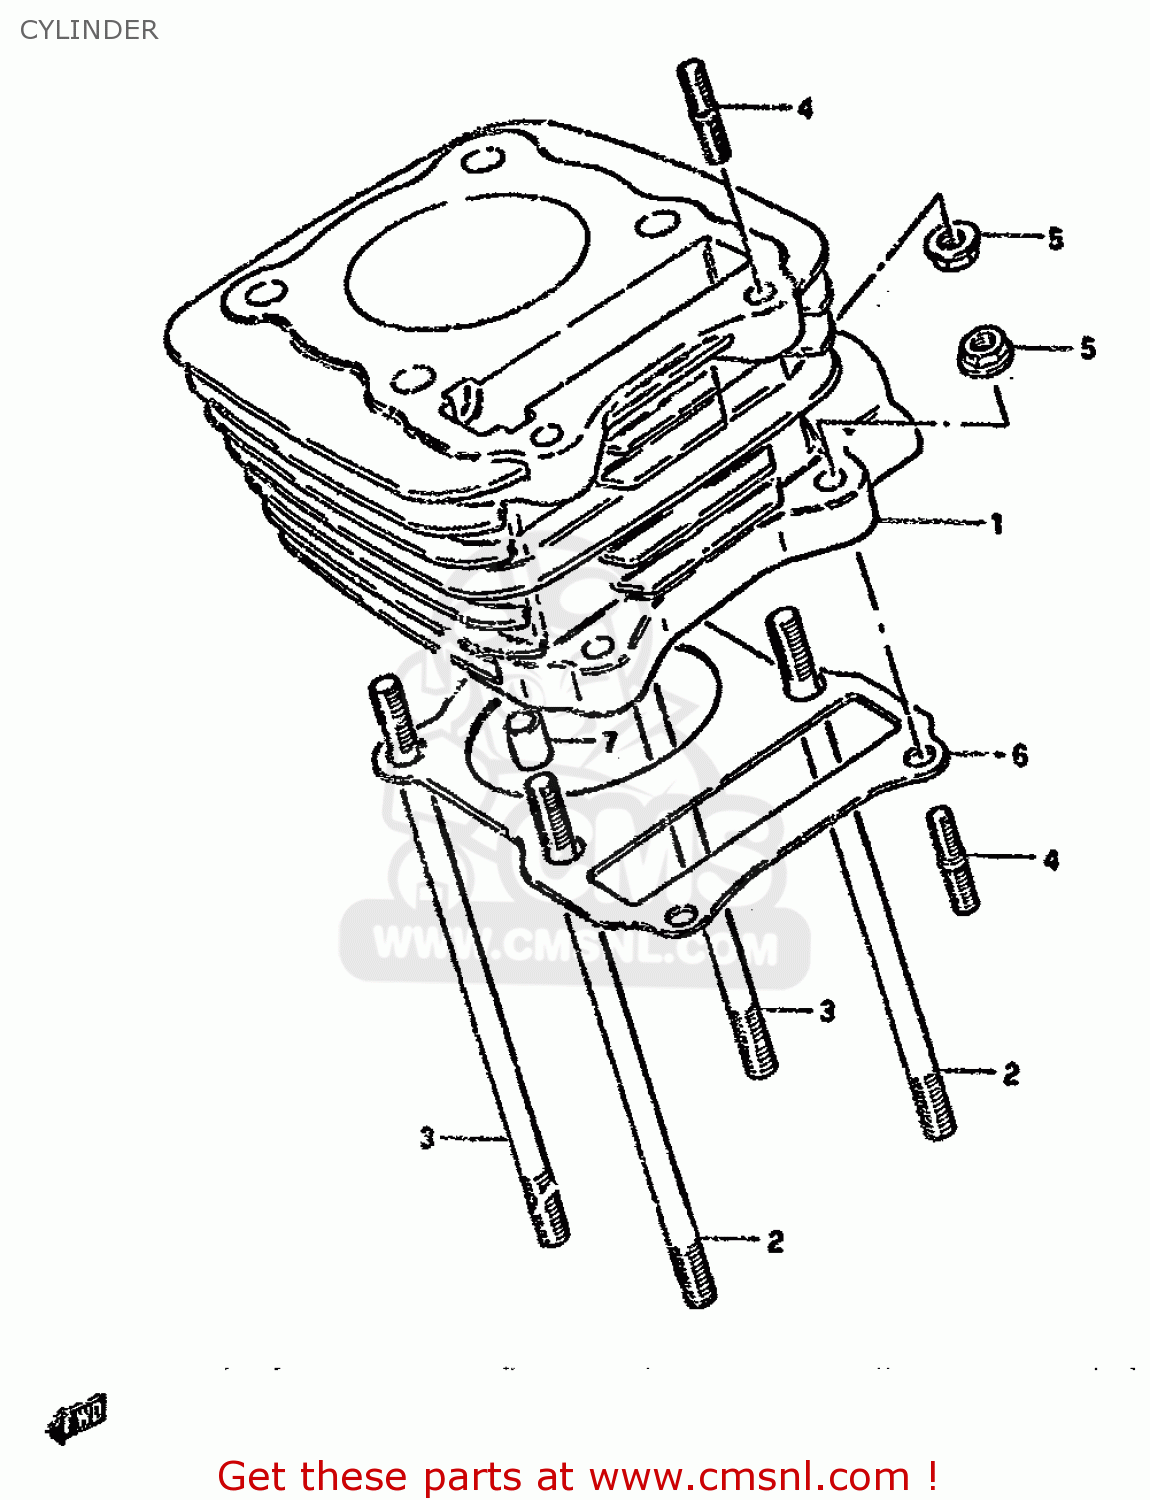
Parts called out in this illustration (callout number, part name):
1	CYLINDER
2	BOLT,STUD
3	BOLT,STUD
4	STUD 6X25
5	NUT 6MM
6	GASKET,CYLINDER (MCA)
7	PIN
